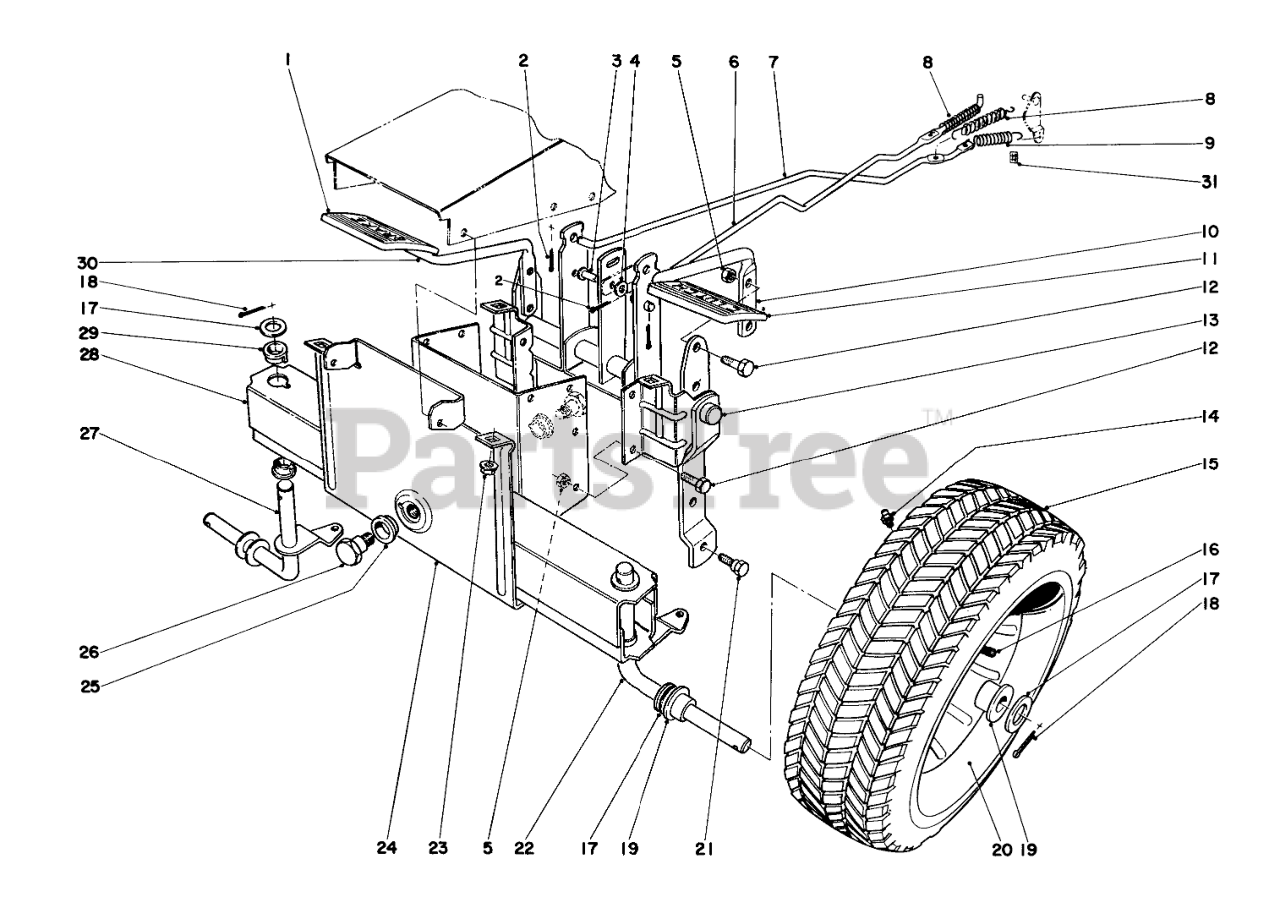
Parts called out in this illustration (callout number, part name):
1	PAD-BRAKE
2	PIN-COTTER
3	PIN-CLEVIS
4	WASHER-PLAIN
5	NUT-LOCK, CONE
6	Clutch Rod
7	Rod Brake
8	Spring
9	Spring, Brake
10	Clutch Pedal
11	CLUTCH PAD
12	SCREW-HH
13	Control Shaft
14	FITTING-GREASE
15	Tire Turf King
16	STEM-VALVE
17	WASHER-FLAT
18	PIN-COTTER
19	BUSHING
21	Screw
22	Spindle L.H.
23	NUT-HF
24	Frame Lower Front
25	Bushing
27	Spindle R.H.
28	Front Axle
29	Bushing
30	Brake Pedal
31	Push on Speed Nut
